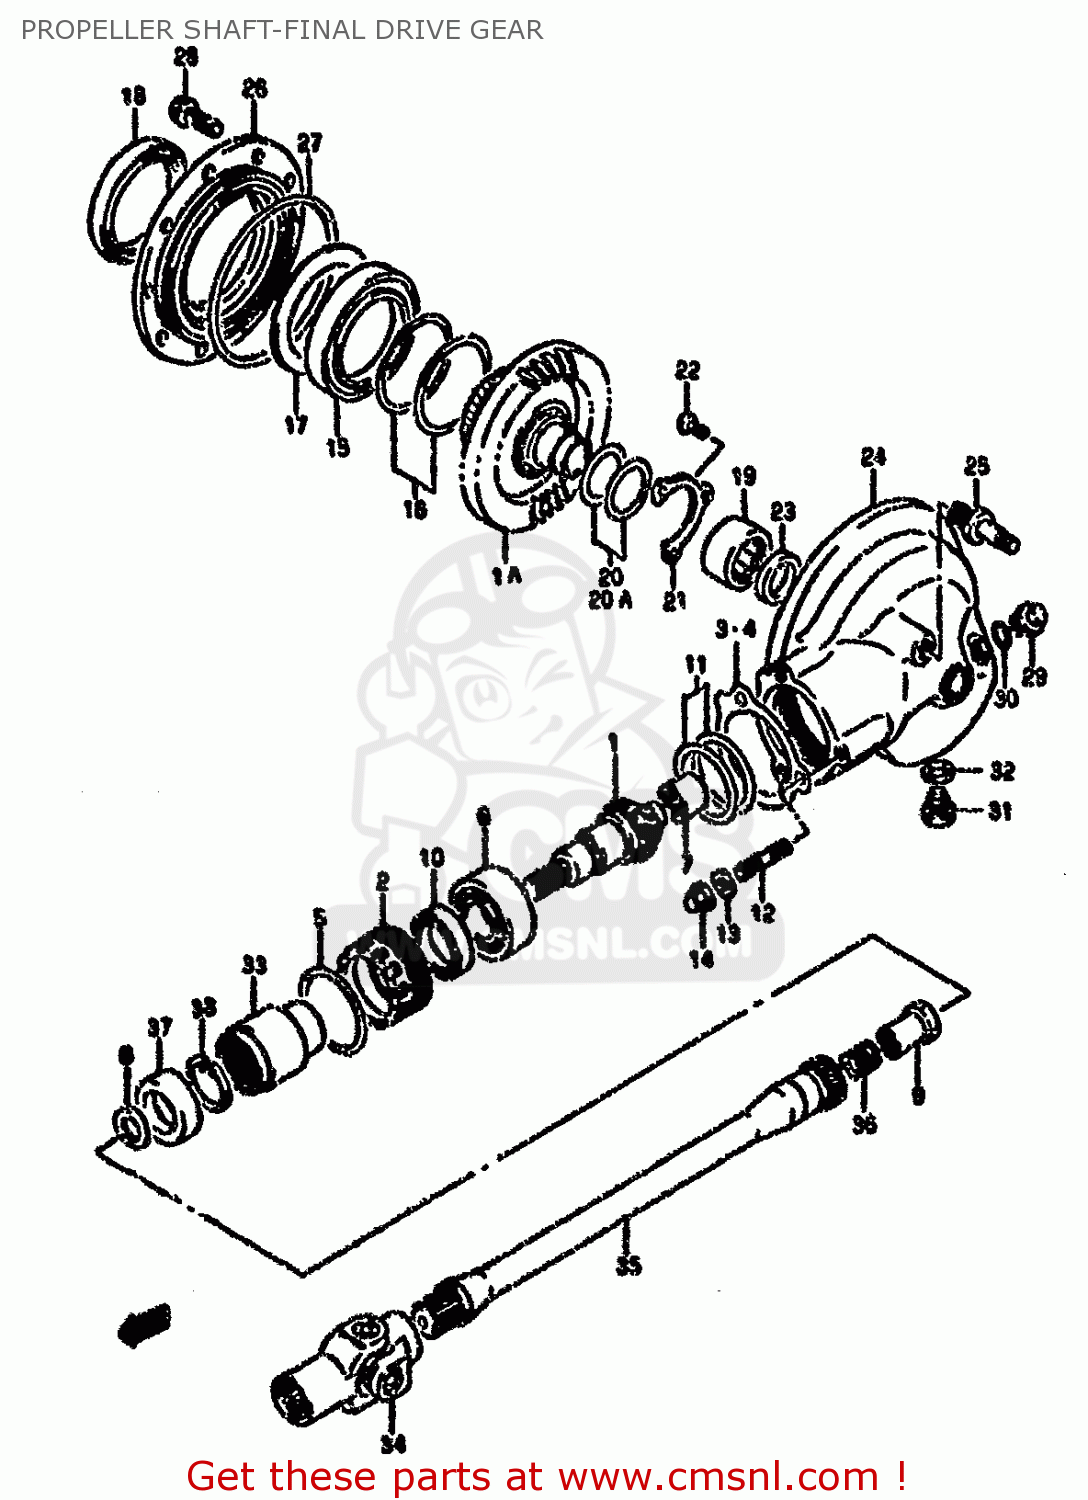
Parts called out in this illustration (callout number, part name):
1	GEAR,FINAL DRIVE BEVEL(NT:11)
1A	GEAR,FINAL DRIVEN BEVEL(NT:34)
2	STOPPER,FINAL DRIVE BEARING
3	PLATE,BEARING STOPPER
4	PLATE,BEARING STOPPER
5	O RING(D:1.9,ID:61.6)
6	BEARING(30X62X23.8)
7	BEARING(17X32X16)
8	WASHER(16X29X4)
9	NUT
10	SEAL,OIL(38X54X6)
11	SHIM SET,FINAL DRIVE GEAR
12	BOLT,STUD
13	WASHER
14	NUT
15	BEARING(70X110X13)
16	SHIM SET,DRIVEN GEAR BEARING
17	PLATE,FINAL DRIVEN BRG OIL
18	SEAL,OIL(70X96X16)
19	BEARING(32X46X17.7)
20	SHIM SET,FINAL DRIVEN GEAR
20A	SHIM SET,FINAL DRIVE GEAR
21	RETAINER,FINAL DRIVEN GEAR BRG
22	SCREW
23	SEAL,OIL(30X42X7)
24	CASE,FINAL GEAR
25	BOLT,REAR UNIT STUD
26	CASE,FINAL GEAR BEARING
27	O RING(D:3.5,ID:131.6)
28	BOLT
29	PLUG
30	O RING(D:2.4,ID:17.8)
31	PLUG
32	GASKET(14X19.2X2) (NAS)
33	COUPLING,FINAL DRIVE GEAR
34	YOKE COMP,UNIVERSAL JOINT
35	SHAFT,PROPELLER
36	SPRING
37	SEAL,OIL(28.4X48X15)
38	CIRCLIP
